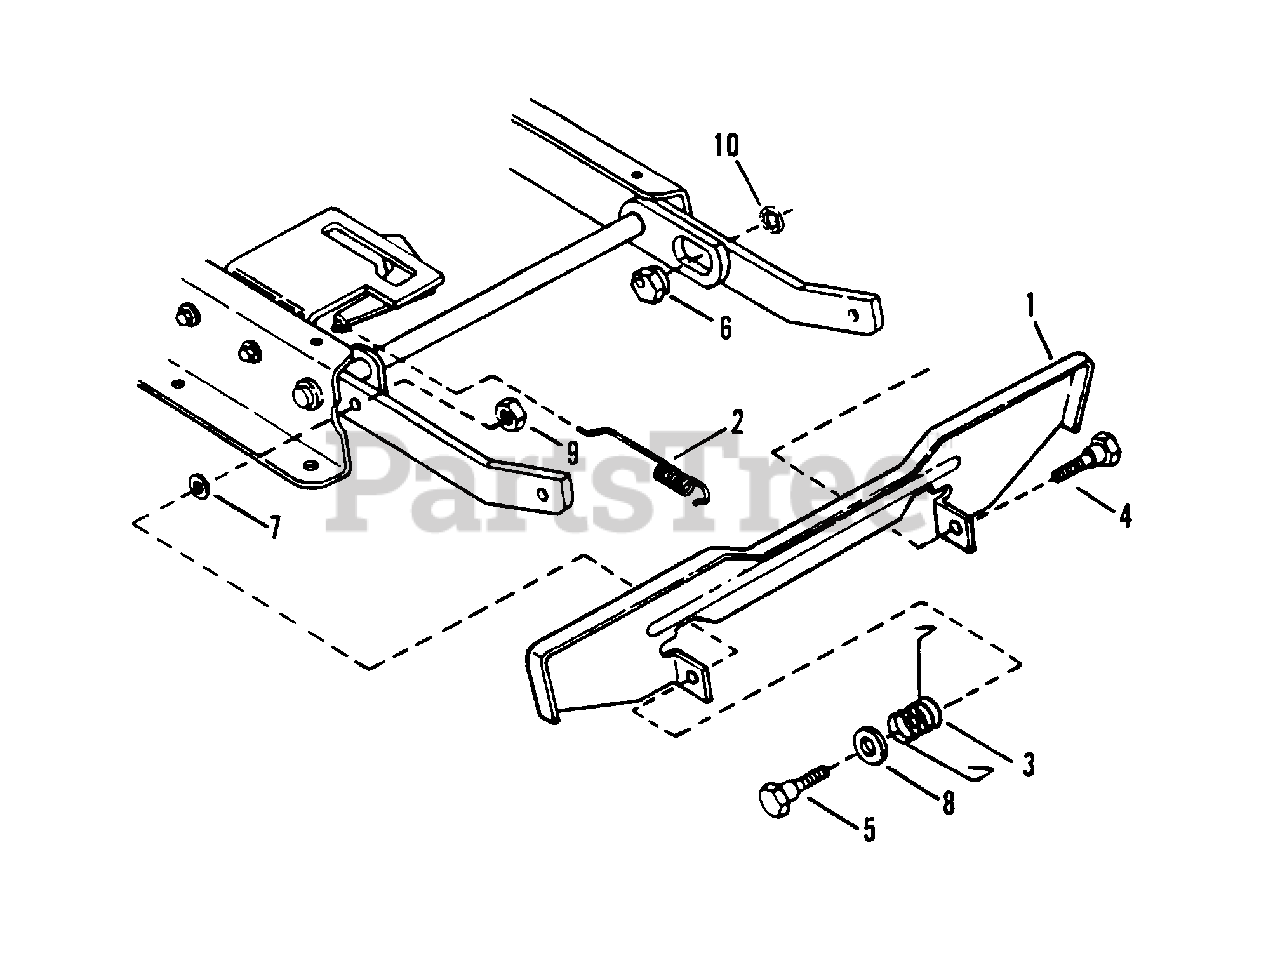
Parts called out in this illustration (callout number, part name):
1	PEDAL, Blade Stop Control
2	SPRING, Latching
3	SPRING, Pedal
4	BOLT, 3/8-24 x 3/4" Shoulder
5	BOLT, 3/8-24 x 9/16" Shoulder
6	ECCENTRIC, Leveling
7	WASHER, 3/8" Flat
8	WASHER, 1/2 Flat
9	NUT, 3/8-24 Hex Lock
10	WASHER, 3/8 Internal Tooth Lock
